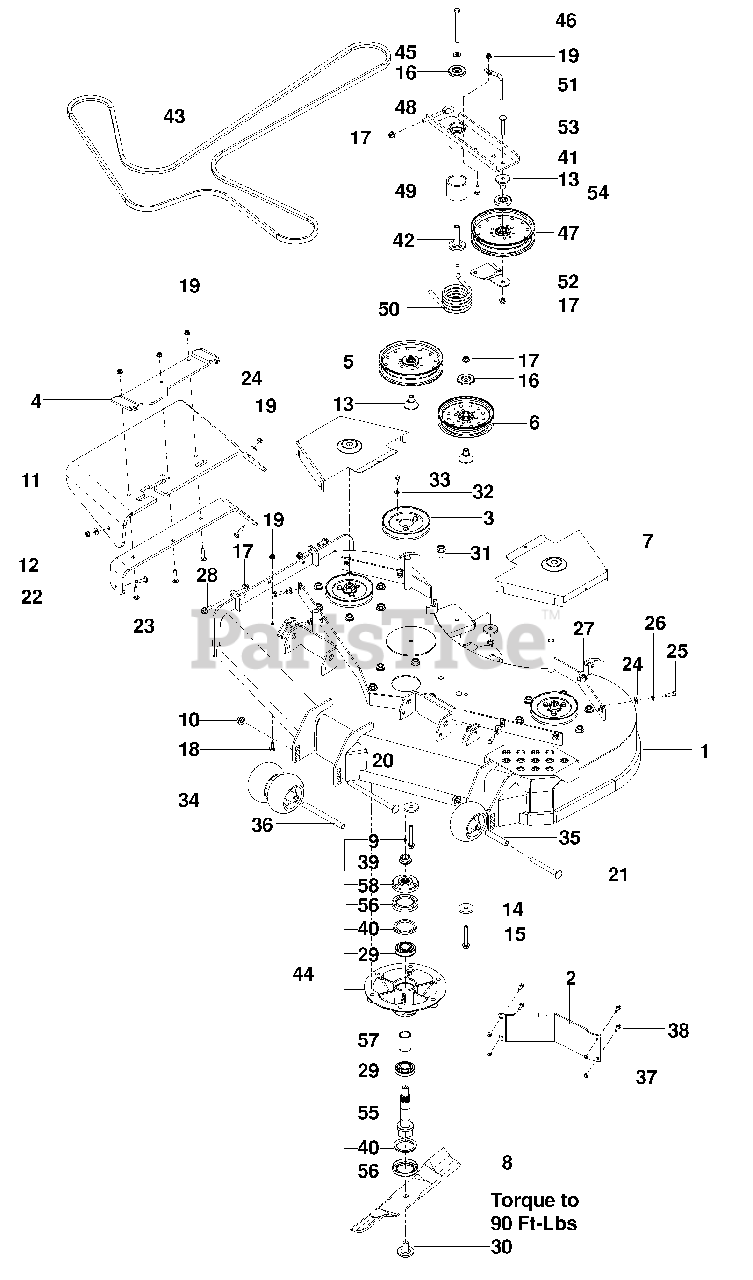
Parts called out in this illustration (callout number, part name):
1	Deck W/ Safety Decals
2	Bolt 7/16-20 X 1 1/2 Hex Nyl
4	Bracket, Chute Pivot
5	Pulley, Idler 7" Narrow
6	Pulley, Idler 6"
7	Shield, Belt
8	Blade, 19"
9	Zerk
10	Nut 1/2-13 Hex Flg Nyloc
11	Chute, Discharge
12	Bracket, Chute Support
13	Bearing, Idler Arm
14	Washer, Heavy
15	Screw 3/8-16 X 2 3/4 Hex Flg
16	Shield, Dust
17	Nut 3/8-16 Hex Flg Nyloc
18	Screw 5/16-18 X 3/4 Hex Flg
19	Nut 5/16-18 Hex Flg Nyloc
20	Bolt 1/2-13 X 8 Rd Hd
21	Bolt 1/2-13 X 4 3/4 Rd Hd
22	Bolt 5/16-18 X 1 1/2 Rd Hd
23	Bolt 5/16-18 X 1 1/4 Rd Hd
24	Washer 5/16 Std Flt
25	Bolt 5/16-18 X 1 Hex Hd
26	Washer 5/16 Slw
27	Retainer, U Type
28	Screw 3/8-16 X 1 Hex Flg
30	Blade Bolt
31	Screw 1/2-13 X 1 Hex Flg
32	Washer 5/16 Disc Spring
33	Bolt 5/16-18 X 1/2 Hex Nyloc
34	Roller, Gauge
35	Tube, Roller Axle
36	Tube, Roller Axle Long
37	Nut 1/4-20 Hex Nyloc
38	Bolt 1/4-20 X 3/4 Carriage
39	Nut 3/4-16 Flg
41	Arm, Idler W/ Brgs, Spacr
42	Bearing, Idler Pivot
43	Belt, Deck
44	Spindle Assy
45	Washer 3/8 Thick
46	Bolt 3/8-16 X 4 1/2 Hex Gr 8
47	Pulley, Idler 7" Wide
48	Eyebolt 3/8 X 4
49	Spacer, Idler Pivot
50	Spring, Torsion
51	Keeper, Belt
52	Guide, Belt
53	Bolt 3/8-16 X 2 1/2 Carriage
54	Bolt 5/16-18 X 1 Rd Hd
55	Shaft, Spindle
56	Cup, Debris
